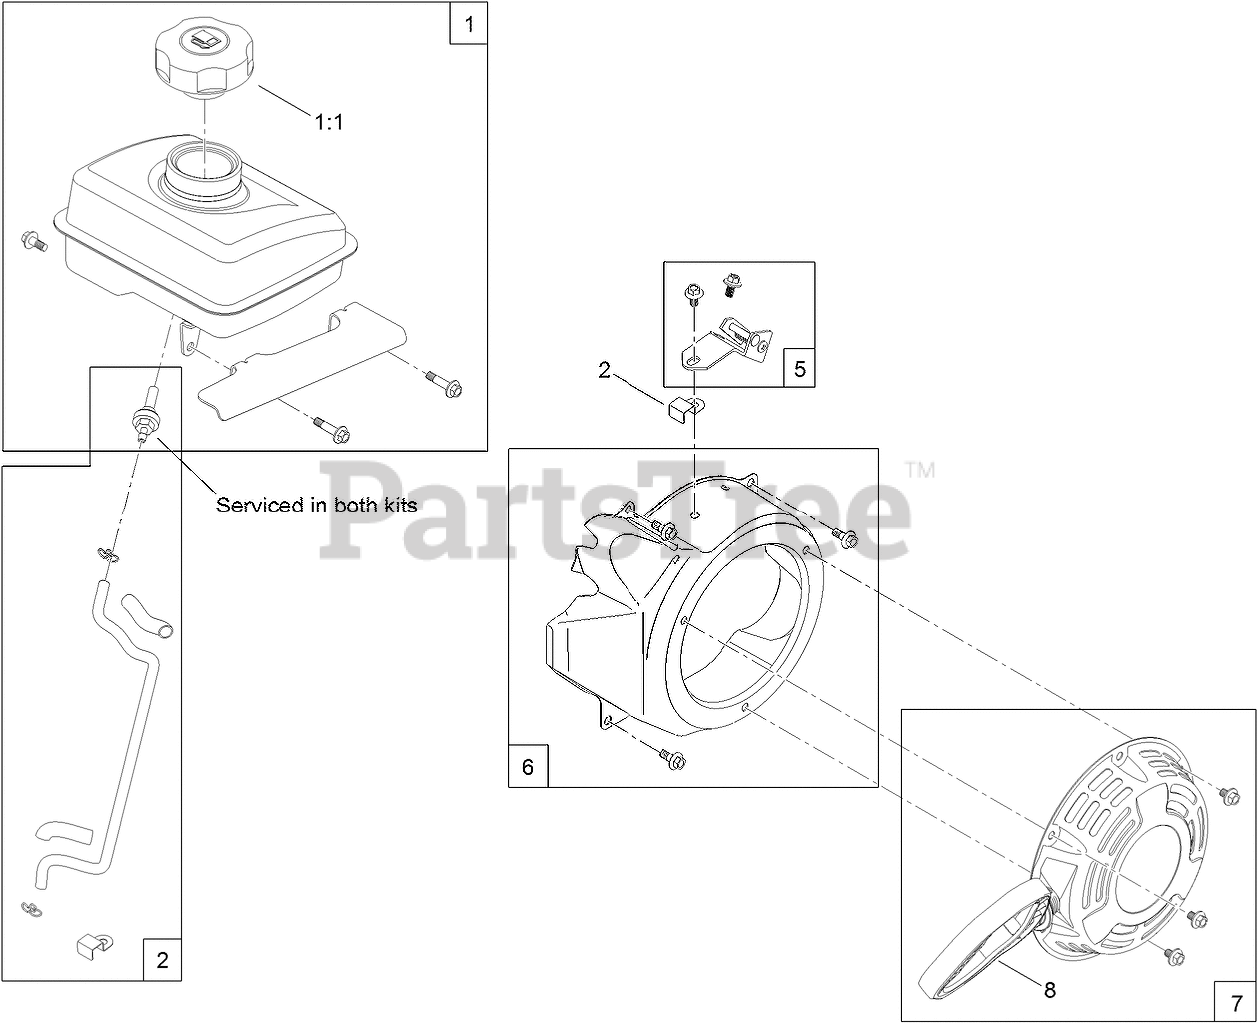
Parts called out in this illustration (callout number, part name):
1	FUEL TANK AND CAP KIT
1:1	CAP-FUEL
2	FUEL LINE KIT
5	GOVERNOR KIT
6	BLOWER SHROUD KIT
7	RECOIL ASM KIT
8	MITTEN GRIP KIT
